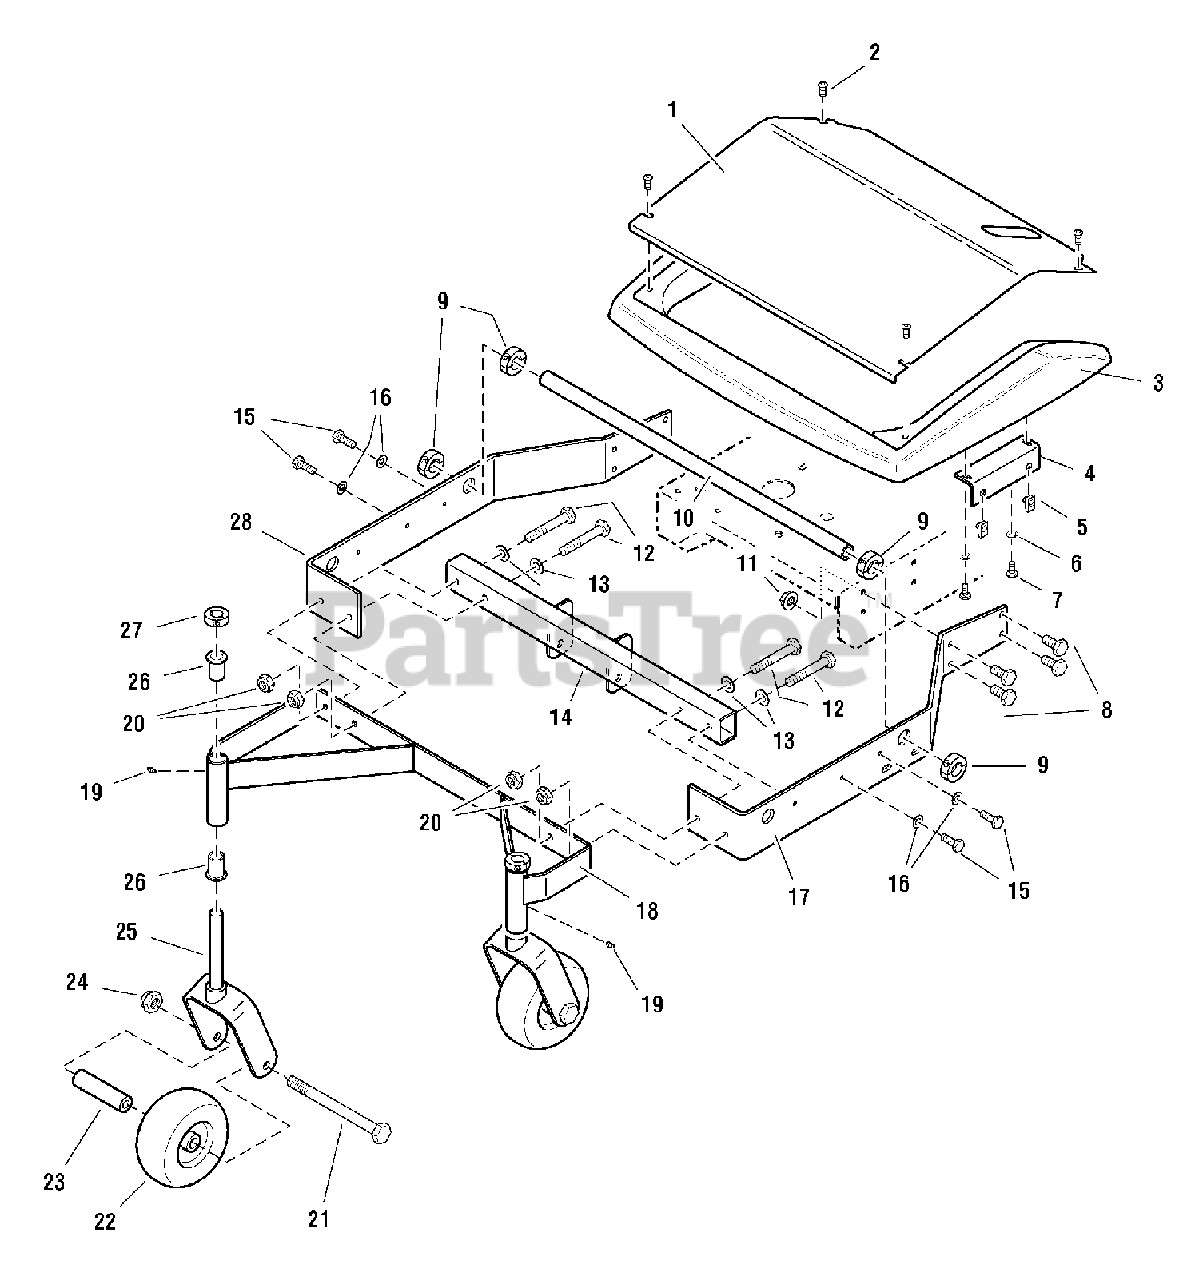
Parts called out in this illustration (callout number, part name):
1	SHIELD INSERT
2	SCREW, Allen Head, 1/4-20 x 1/2
3	GUARD, Mower Deck
4	SHIELD MOUNT BRACKET
5	BODY CLIP, 5/16-18
6	LOCKWASHER, 1/4
7	CAPSCREW, Hex Head, 1/4-20 x 3/4
8	CAPSCREW, Hex Head, 3/8-16 x 1
9	COLLAR, Double Split, 1
11	NUT, Hex Serrated Flange, 3/8-16
12	CAPSCREW, Hex Head, 3/8-16 x 2-1/2
13	WASHER, 3/8
15	BOLT, 1/4-20 X 1", GD
16	WASHER, 5/16
17	FRAME RAIL - LH
18	CASTER MOUNT FRAME
19	GREASE FITTING, 1/4-28
20	NUT, Hex Nylon Lock, 3/8-16
21	CAPSCREW, Hex Head, 1/2-13 x 5-1/2
22	CASTER TIRE
24	NUT, Hex Nylon Lock, 1/2-13
25	CASTER YOKE
26	BUSHING, Flange
27	COLLAR, Split, 3/4
28	FRAME RAIL - RH
